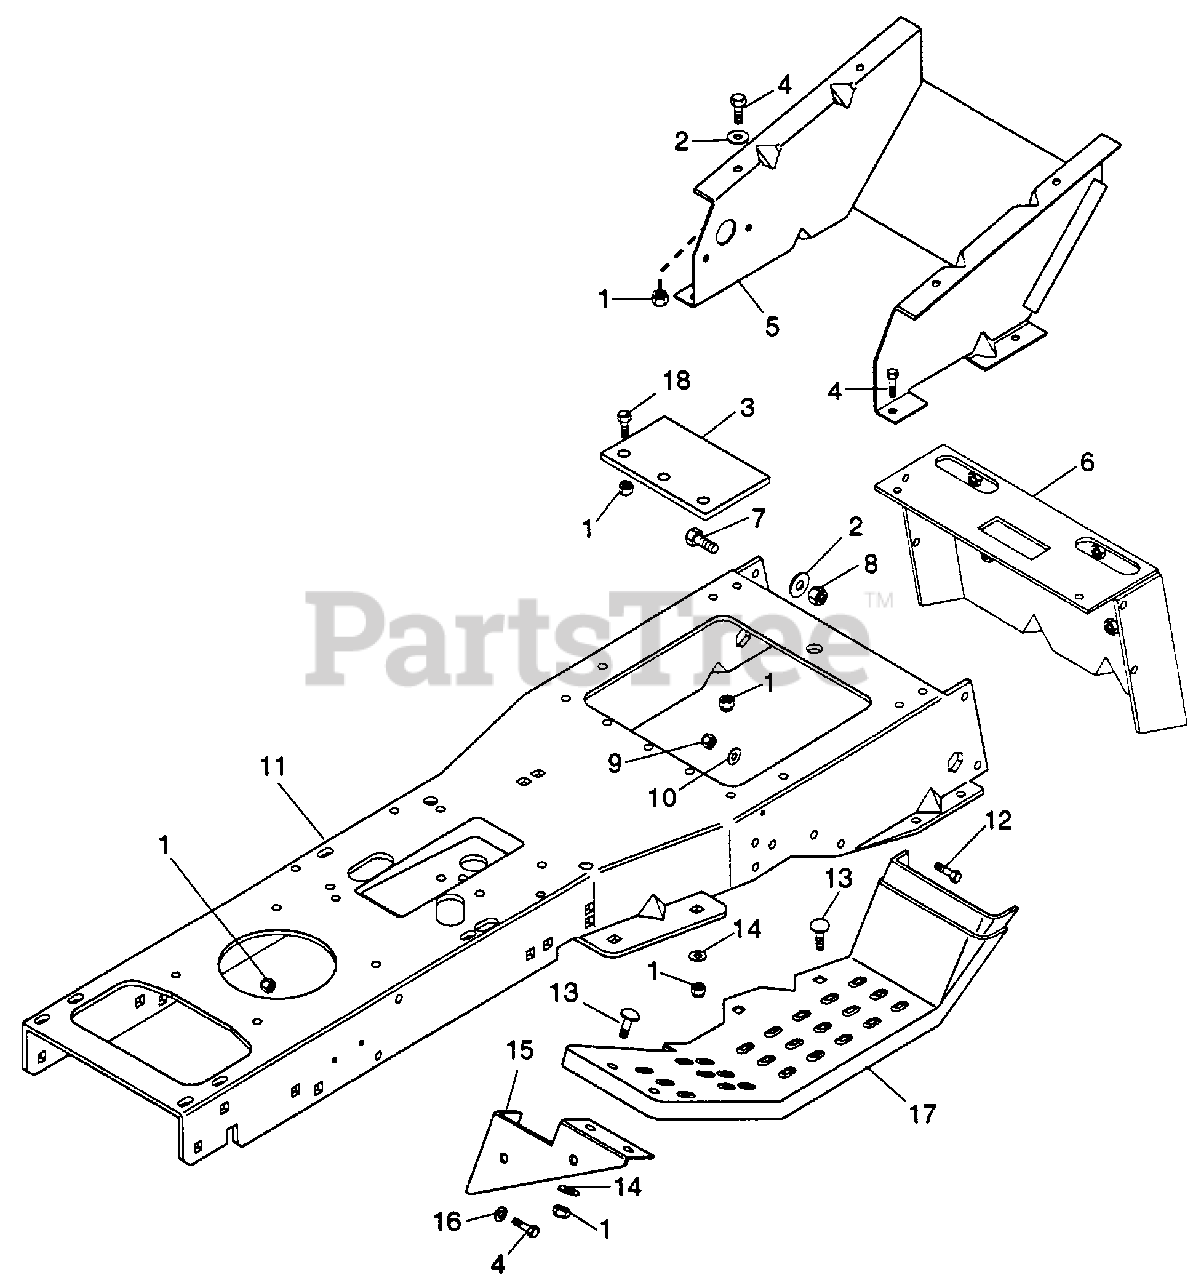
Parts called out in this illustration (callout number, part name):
1	Nut-Lk-Nly .312 - 18 Pl
2	Washer, Flt .375 x 1.125 x .065
3	Support Plate
4	Blt-Rdhdsqnk .38-16 x 1.75 Pl
5	Torque Strap - R
6	Tailboard
7	Blt-Hex .380 - 16 x .875
8	Nut-Lk-Nyl .375 - 16 Pl
9	Nut-Lk-Nyl .250 - 20 Pl
10	Wshr-Fl-Stl .281 x .625 x.065
11	Frame
12	Blt-Hex .25-20 x .75 Pl Gr 5
13	Blt-Carriage .31-18 x 1.0
14	Wshr-Fl-Stl .344 x .688 x .065
15	L. Foot Rest Brace
15	R. Foot Rest Brace
16	Wshr-Fl-Stl .313 x .875 x .065
17	Footrest LH
17	Footrest RH
18	Blt-Hex .31-18 x .75 Pl Gr 5
NS	Decal - Trans Lock Out
NS	Decal - Caution
